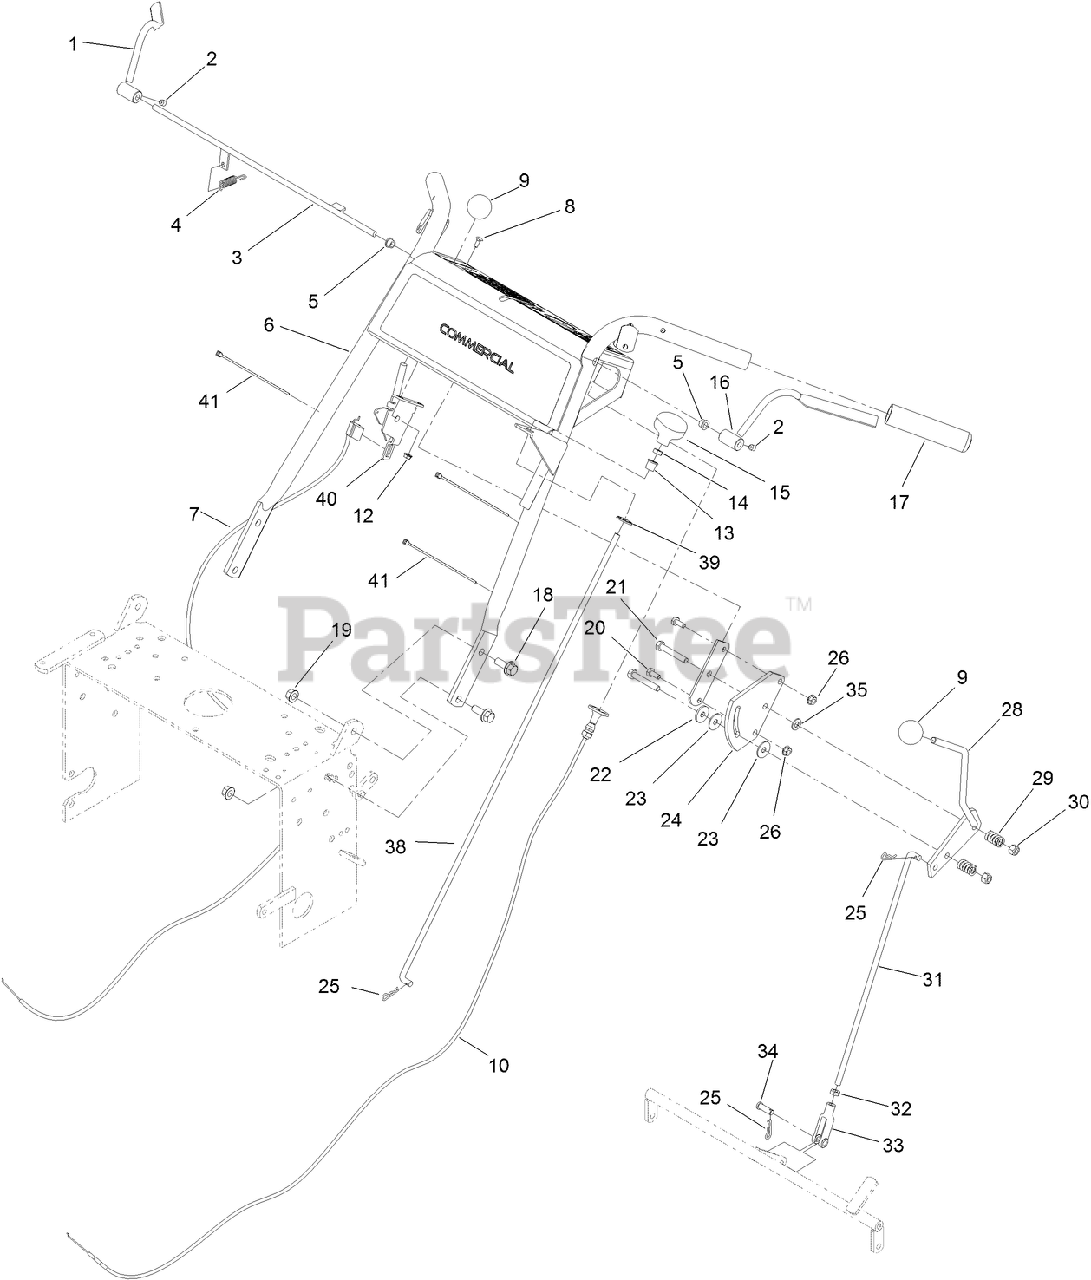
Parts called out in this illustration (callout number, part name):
1	RH OPERATOR PRESENCE CONTROL LEVER ASM
2	SCREW-SET
3	ROD-CONTROL, OPERATOR PRESENCE
4	SPRING-EXTENSION
5	BUSHING-NYLON
6	HANDLE ASM
7	CABLE-CONTROL
8	BOLT-CARR
9	KNOB-BALL
10	CONTROL, CHOKE
12	NUT-LOCK, FLANGE
13	BEARING-NYLON
14	NUT-JAM
15	KNOB-PUSH / PULL
16	LH OPERATOR PRESENCE CONTROL LEVER ASM
17	GRIP-FOAM
18	SCREW-HHF
19	NUT-HF
20	SCREW-HH
21	SCREW-HH
22	WASHER-FRICTION
23	WASHER-FRICTION
24	PLATE-LEVER, SHIFTER
25	PIN-COTTER
26	NUT-HF
28	LEVER-SHIFT
29	SPRING-COMPRESSION
30	NUT-LOCK, NI
31	ROD-CONTROL, SPEED
32	NUT-JAM
33	YOKE-ADJUSTABLE
34	PIN-CLEVIS
35	WASHER-PLAIN
38	LINKAGE-BLADE
39	NUT-PUSH
40	LEVER-CONTROL
41	TIE-CABLE
